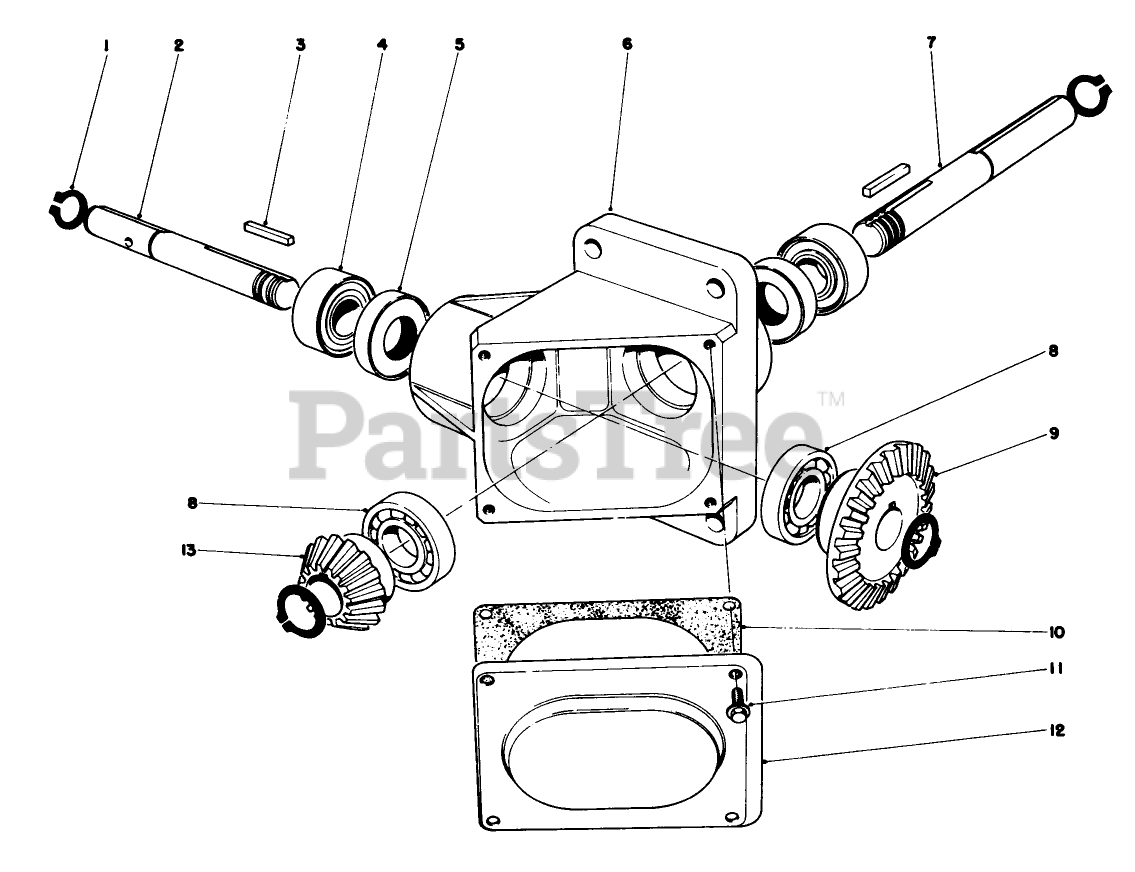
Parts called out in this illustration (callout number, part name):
1	Ring-Snap
2	GEAR BOX SHAFT (60120
3	Key
4	ROLLER BEAR (60124)
5	Oil Seal
6	GEAR BOX HSG
7	SHAFT-GEAR BOX
8	BEARING (R-12)
9	BEVEL GEAR (60128)
10	GASKET (60129)
11	SCREW
12	Cover Plate
13	BEVEL GEAR (60121)
